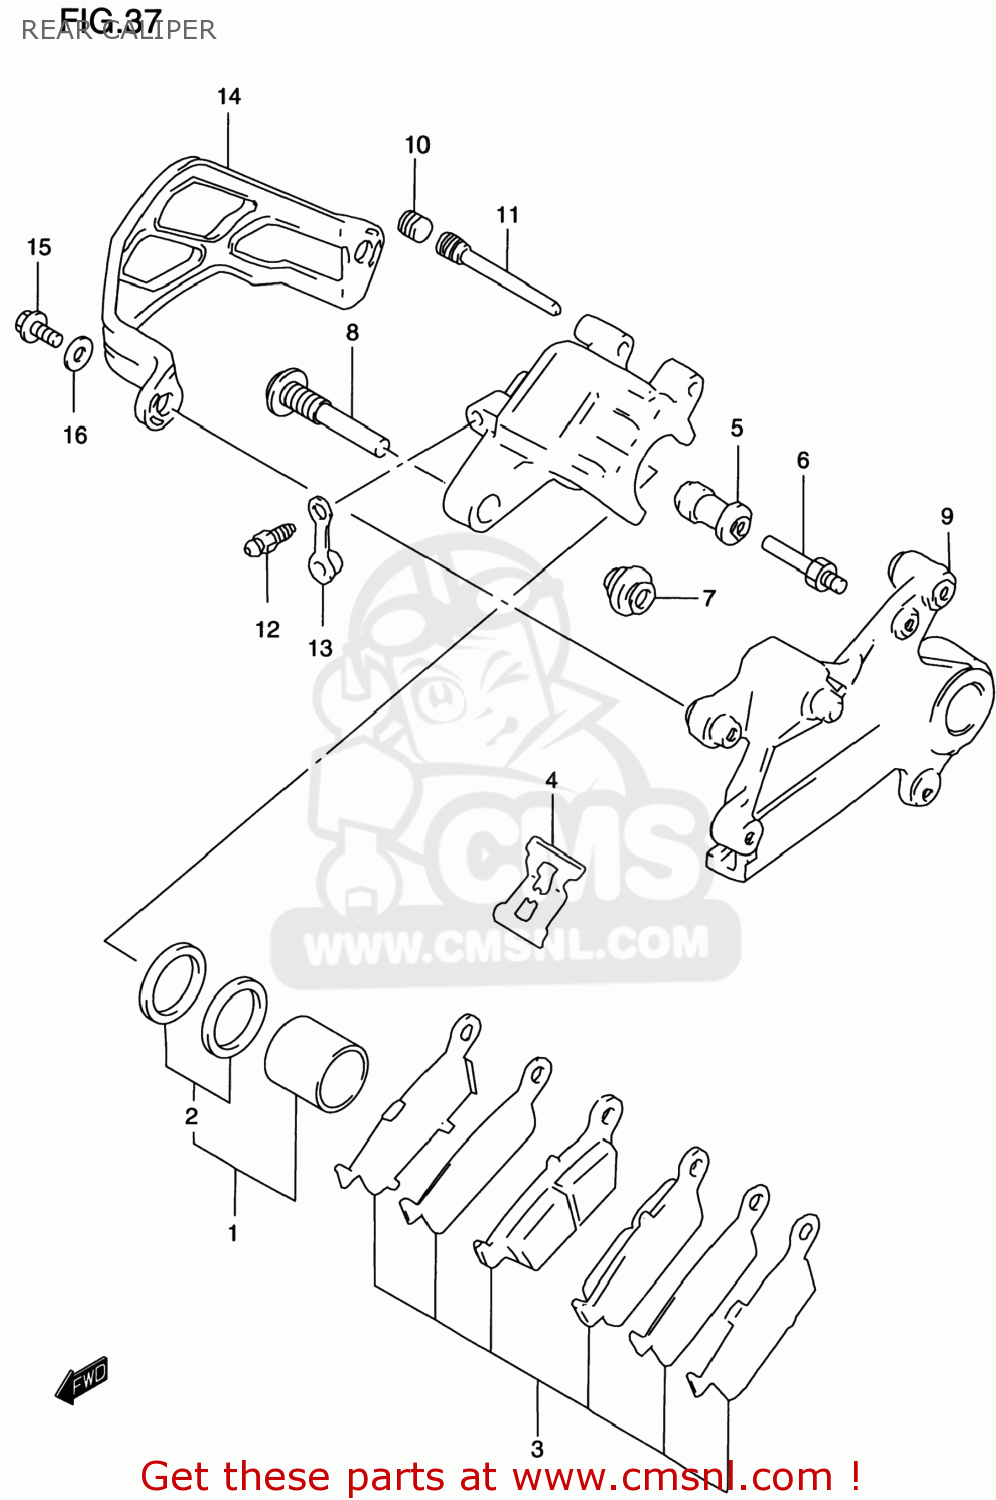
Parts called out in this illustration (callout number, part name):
1	PISTON SET
2	SEAL SET,PISTON
3	PAD & RETAINER SET
4	SPRING,PAD
5	BOOT
6	BOLT
7	BOOT
8	PIN,BOLT
9	BRACKET
10	PLUG,PIN
11	PIN,HANGER
12	BLEEDER
13	CAP,BLEEDER
14	GUARD,RR CALIPER
15	BOLT
16	WASHER
